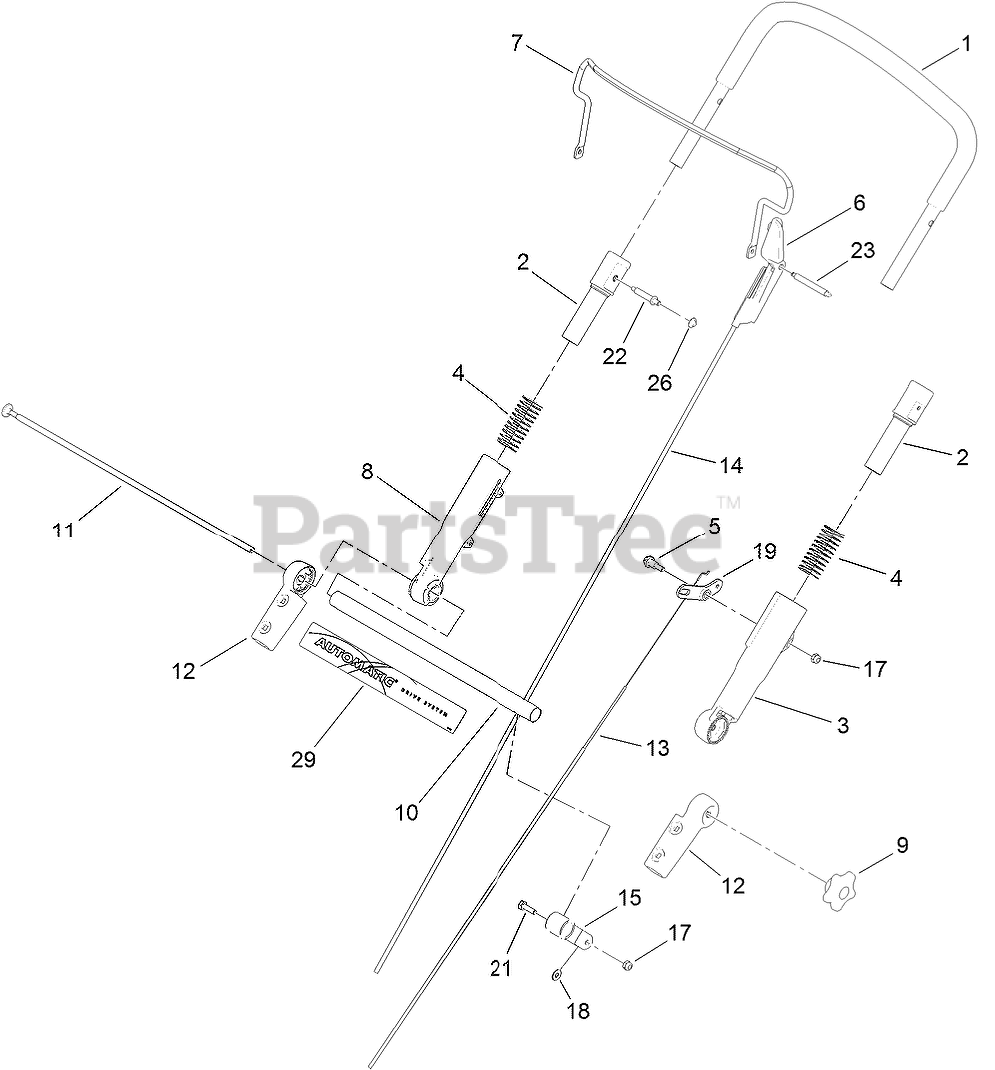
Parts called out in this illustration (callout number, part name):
1	UPPER HANDLE ASM
2	SLEEVE-INNER
3	SLEEVE-OUTER, LH
4	SPRING-COMPRESSION
5	BOLT-SHOULDER
6	STOP-PIVOT
7	BAIL-BRAKE
8	SLEEVE-OUTER, RH
9	KNOB-HANDLE
10	TUBE-CROSS
11	ROD-THREADED
12	MOUNT-HANDLE, LOWER
13	CABLE-TRACTION
14	CABLE-BRAKE
15	CLAMP-CABLE
17	NUT-LOCK, NI
18	WASHER-FLAT
19	LEVER-TRACTION
21	SCREW-HH
22	PIN-HANDLE
23	PIN-BAIL, LH
26	RETAINER-PUSH ON
29	DECAL-ADS
